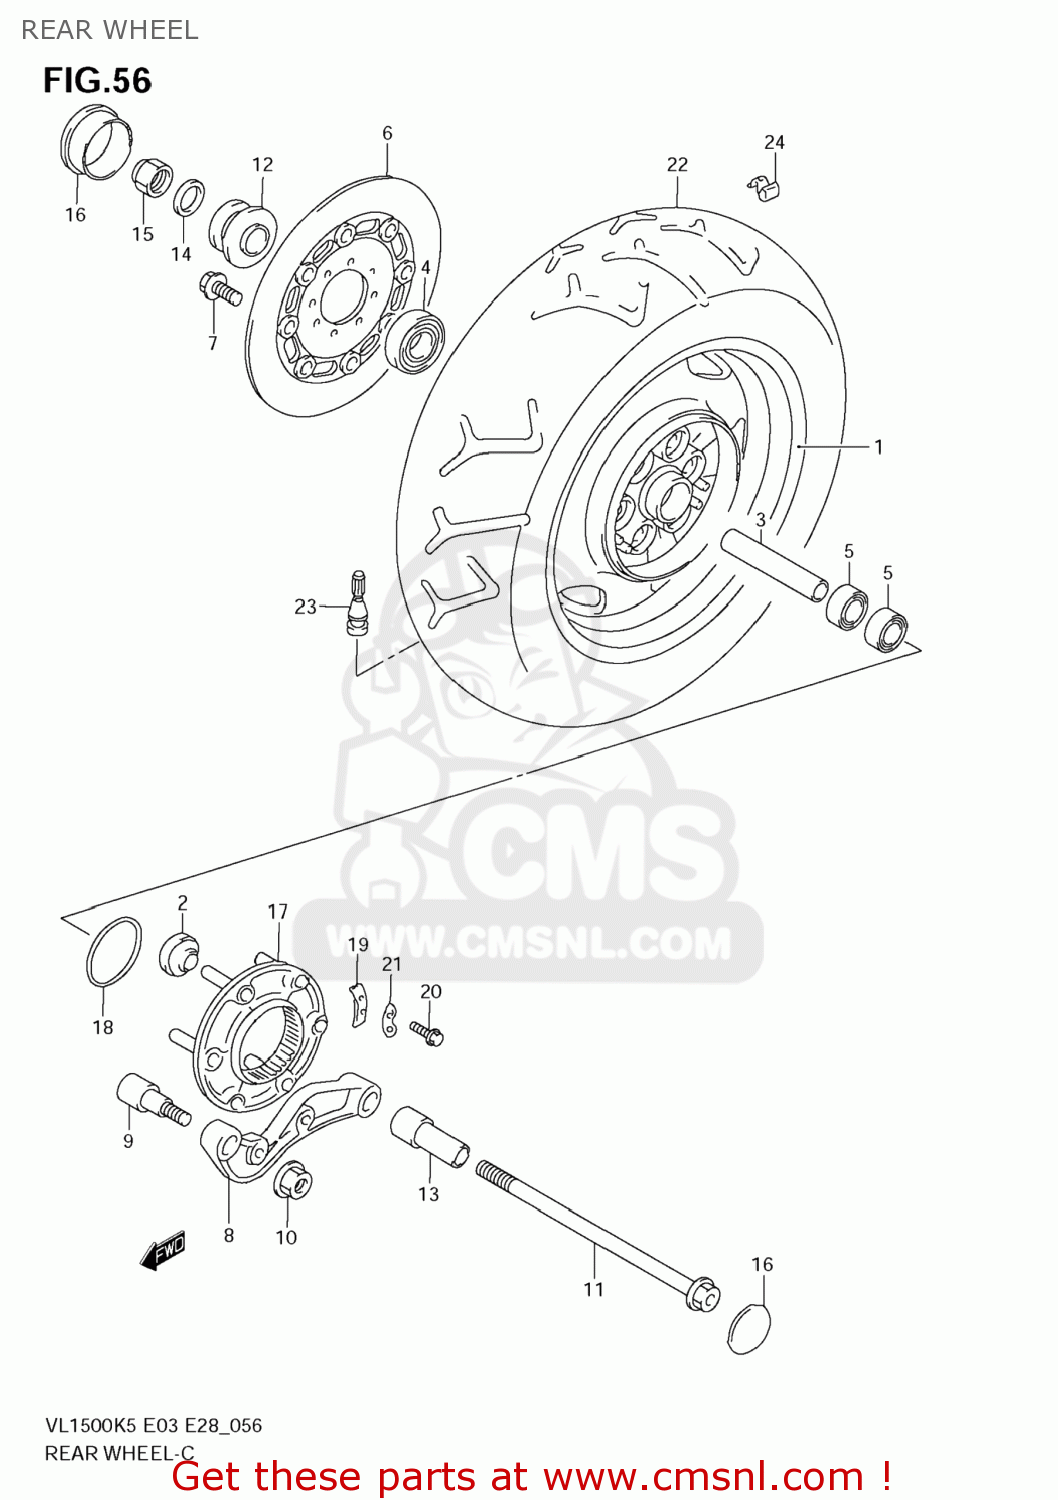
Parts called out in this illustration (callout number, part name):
1	WHEEL SET,RR(MT5.00X15)
2	BUSH
3	SPACER(20.8X27.2X124)
4	BEARING WHEEL REAR(20X47X14)
5	BEARING(20X47X14)
6	DISC,REAR BRAK
7	BOLT(8X33)
8	BRACKET,RR CALIPER
9	PIN,CALIPER BRACKET
10	NUT
11	AXLE,RR
12	SPACER,RR AXLE,R
13	SPACER,RR AXLE,L
14	WASHER
15	NUT
16	CAP,RR AXLE,L
17	JOINT ASSY,RR HUB DRIVEN
18	O RING(D:2.1,ID:65)
19	WASHER,THRUST(T:1.6)
20	BOLT(6X16)
21	WASHER
22	TIRE,RR
23	VALVE ASSY,WHEEL RIM(TR412)
24	WEIGHT,WHEEL BALANCE 10G
